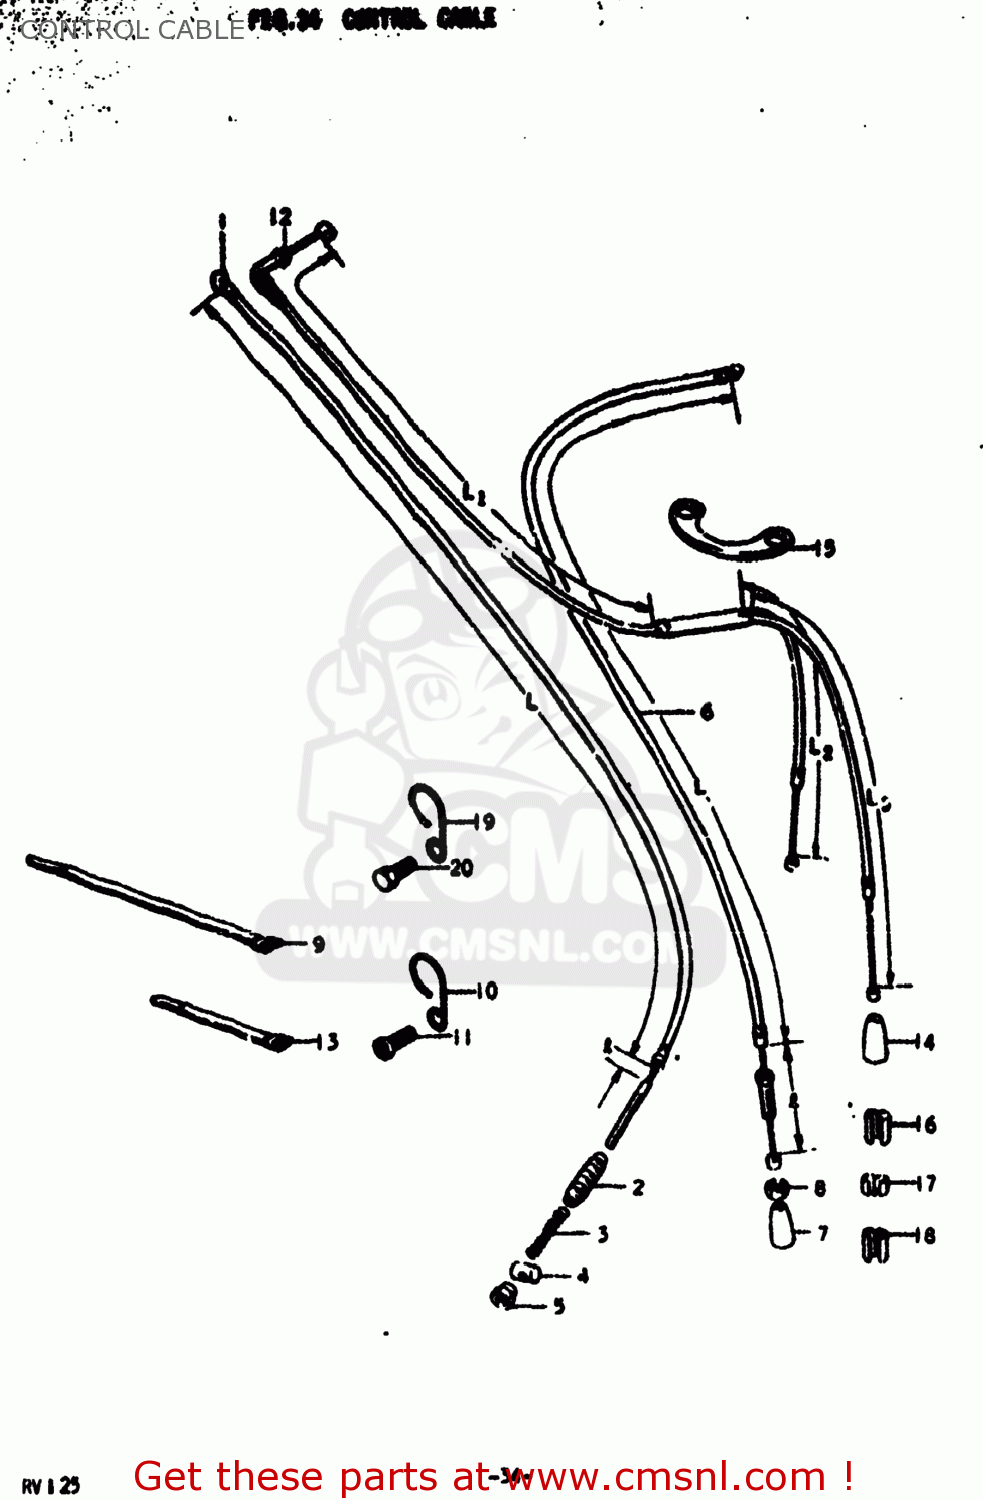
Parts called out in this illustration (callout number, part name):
1	CABLE ASSEMBLY,FRONT BRAKE
2	SEAL,DUST(7X16X75)
3	SPRING
4	PIN,10X19
5	NUT
6	CABLE ASSY,CLUTCH
7	SEAL,DUST(7X18X30)
8	NUT
9	CLAMP
10	CLIP
11	SCREW 6X12
12	CABLE ASSEMBLY,THROTTLE
13	CLAMP
14	SEAL,DUST(7X18X30)
15	GUIDE,CABLE
16	CLIP
17	CLIP
18	CLAMP
19	GUIDE,CABLE
20	BOLT
